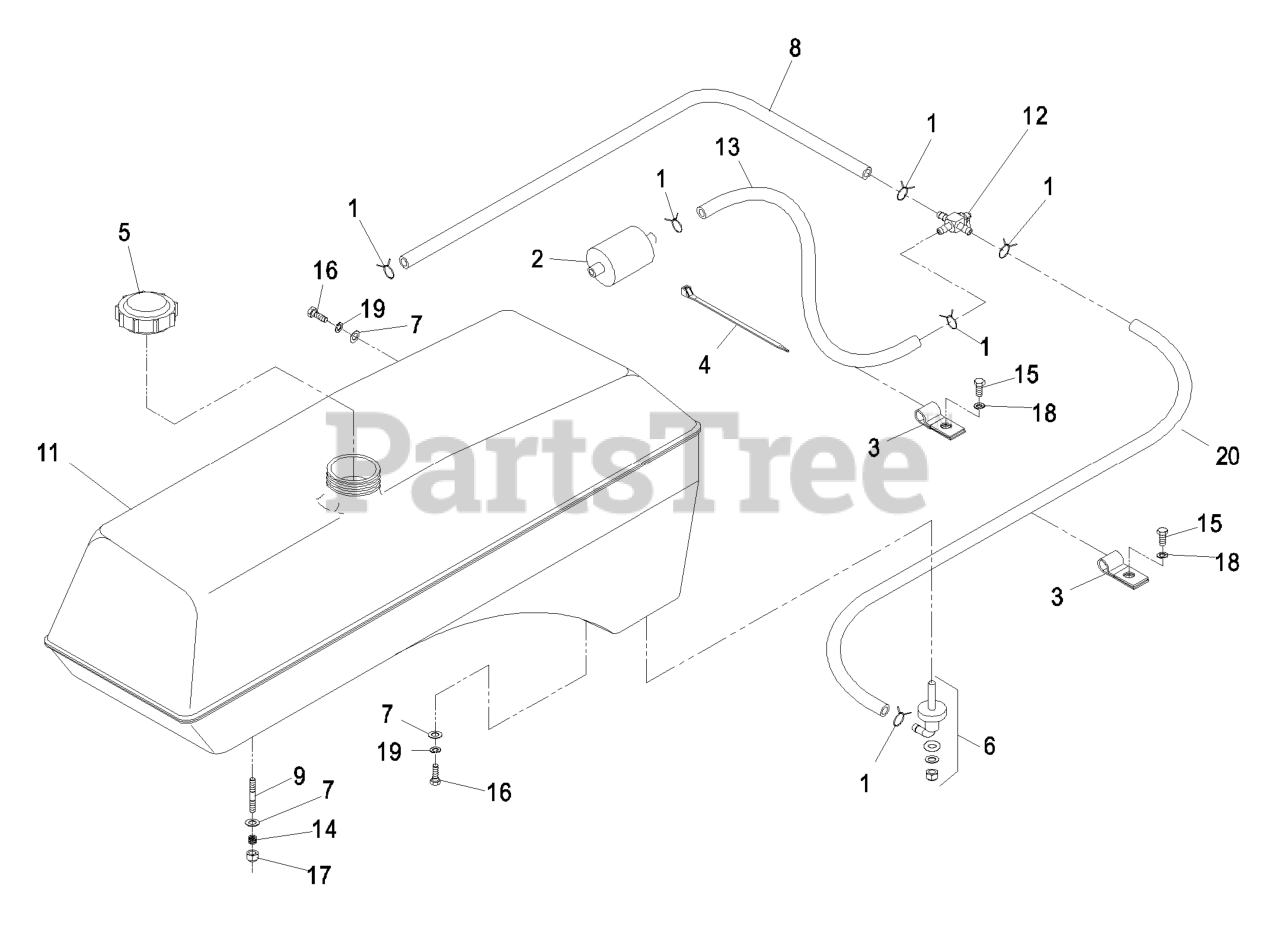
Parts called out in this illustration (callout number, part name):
2	Kohler Part No. 2405002 Fuel Filter
3	CLIP-LOOM
4	TIE-PLASTIC
5	CAP-FUEL
6	FITTING-FUEL, BULKHEAD
7	WASHER-PLAIN
8	HOSE-FUEL
9	STUD
12	VALVE-FUEL
14	SPRING-TANK, FUEL
15	SCREW-HH
16	SCREW-HH
17	NUT-LOCK, NI
18	WASHER-LOCK
19	WASHER-LOCK
20	HOSE-FUEL
